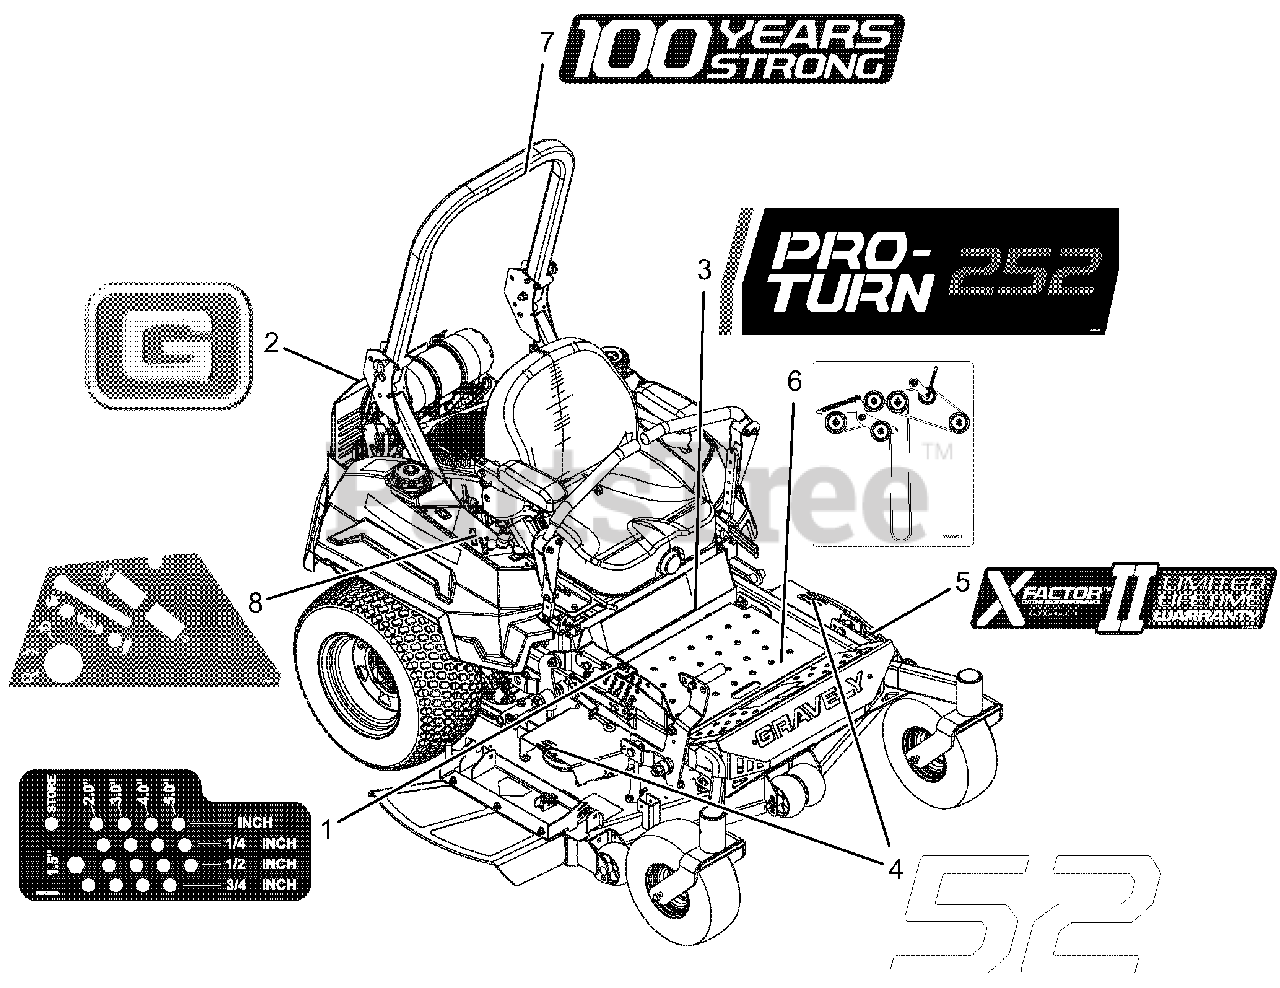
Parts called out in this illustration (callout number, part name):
1	DECAL, HEIGHT OF CUT
2	DECAL, GRAVELY BRAND
3	DECAL, PRO-TURN 252
4	DECAL, 52"
5	DECAL, X-FACTOR DECK
6	DCL,BELT ROUTE-RH V-SIDE IDLER
7	DECAL, GRAVELY 100 YR
8	DECAL, EFI CONTROL PANEL
